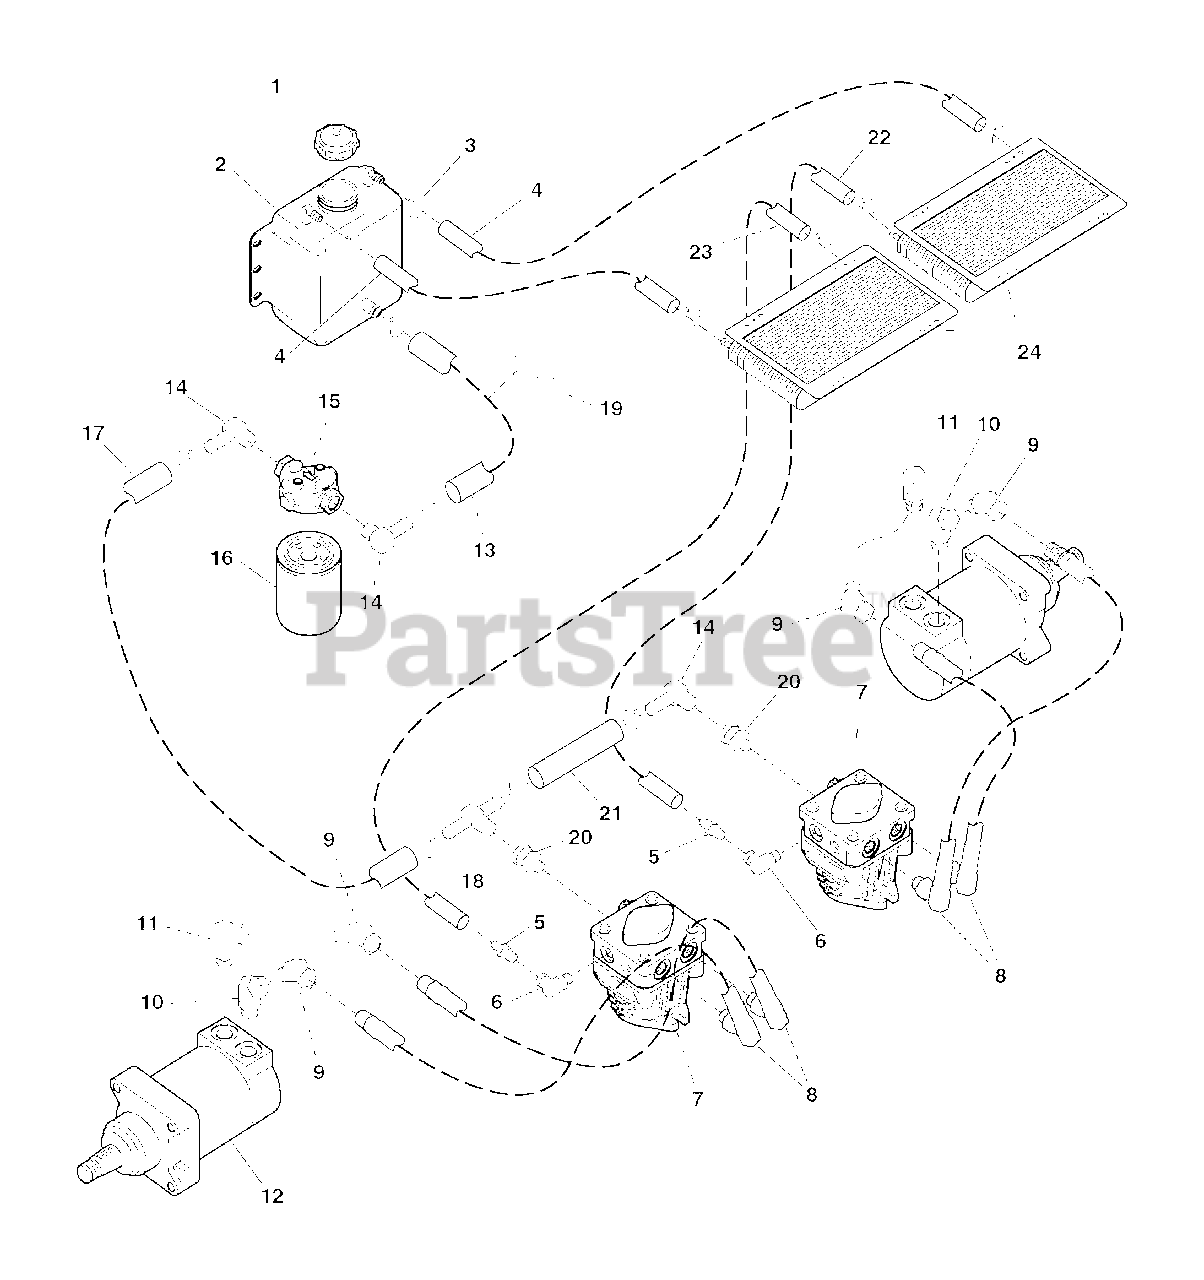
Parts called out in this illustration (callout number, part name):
4	HOSE, Return
5	FITTING, Hose, Straight
6	FITTING, Hydraulic, 90 Deg. O-Ring Swivel
7	HYDRAULIC PUMP
9	FITTING, Hydraulic, 45 Deg. Swivel
10	FITTING, Hydraulic, 45 Deg. O-Ring Swivel
11	FITTING, Hydraulic, 90 Deg. O-Ring Swivel
12	HYDRAULIC WHEEL MOTOR
13	HOSE, Supply (Tank to Filter)
14	FITTING, Hose, 90 Deg.
15	FILTER HEAD
16	HYDRAULIC FILTER
17	HOSE, Supply (Filter to LH Pump)
18	FITTING, Hose Tee
19	SPRING, Compression
20	FITTING, Hydraulic, Straight Swivel
21	HOSE, Supply (LH Pump to RH Pump)
22	HOSE, Return
23	HOSE, Return
